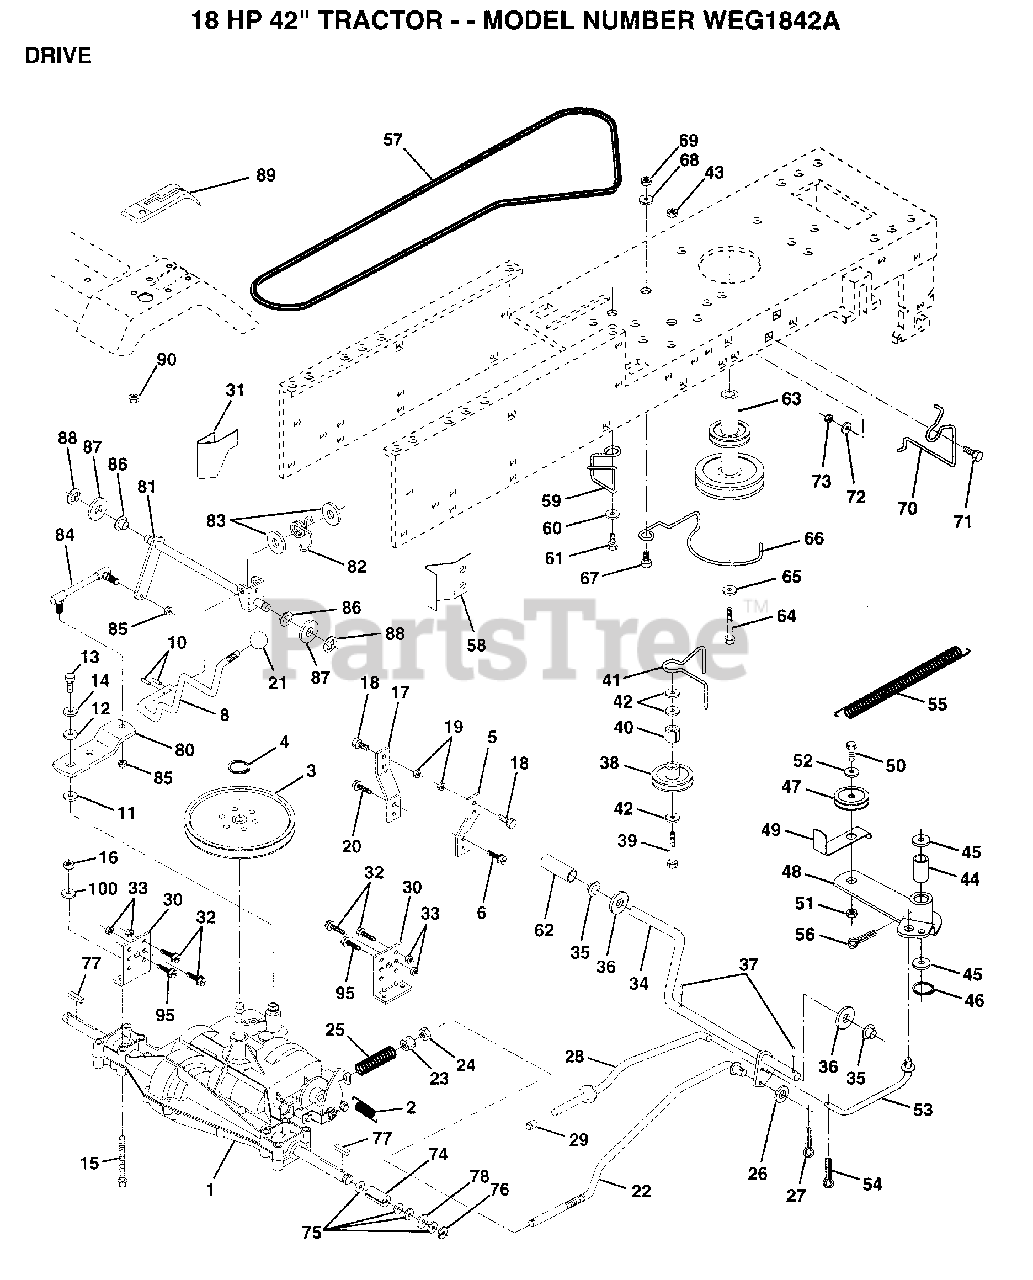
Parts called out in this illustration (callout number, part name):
3	PULLEY TRANS
5	STRAP TORQUE
6	SCREW
8	ROD SHIFT FEND LT
10	PIN COTTER 1/8
11	WASH-SHFT PLT LT
12	WASHER
14	LOCKWASHER
15	BOLT HEX
16	NUT
17	STRAP TORQUE
18	BOLT
19	NUT
20	SCREW
21	KNOB T (1/2-HOLE)
22	BRAKE ROD
23	NUT
24	NUT
25	SPRING ROD LT
26	WASHER
27	COTTER PIN
28	BRAKE PARK ROD
29	PLUNGER CAP T
30	TRANSAXLE MTG BKT
31	"KEEPER,BELT LH T"
32	BOLT
33	NUT
35	NYLON BEARING
36	WASHER LT
38	PULLEY.IDLER.FLAT
39	BOLT
40	SPACER T
41	BELT KEEPER LT
42	WASHER
43	NUT
44	"LY, BEARING"
45	WASHER LT
46	KLIP RING
48	ARM IDLER
49	RETAIN BELT
52	WASHER
53	"LINK, CLUTCH T"
54	COTTER PIN
55	"SPRING, RETURN LT"
56	COTTER PIN
58	"KEEPER,BELT RH T"
59	KEEPER BELT CNTSP
60	WASHER
61	SCREW
62	PEDAL COVER T
63	PULLEY.ENGINE
64	BOLT
65	LOCKWASHER
66	KEEPER.BELT.ENG.L
67	BOLT
68	WASHER
70	KEEPER BELT ENG
71	BOLT
72	WASHER
74	SPACER LT
75	WASHER
76	E-RING LT
77	SQUARE KEY
78	WASHER
80	ARM SHIFT TRANS
81	SHAFT ASM.SHIFT
82	"SPRING,TORSION"
83	WASHER
84	TIE ROD
85	NUT 1/4-28
86	BUSHING
87	WASHER D
88	KLIP RING
90	NUT
95	SCREW
100	WASHER M
